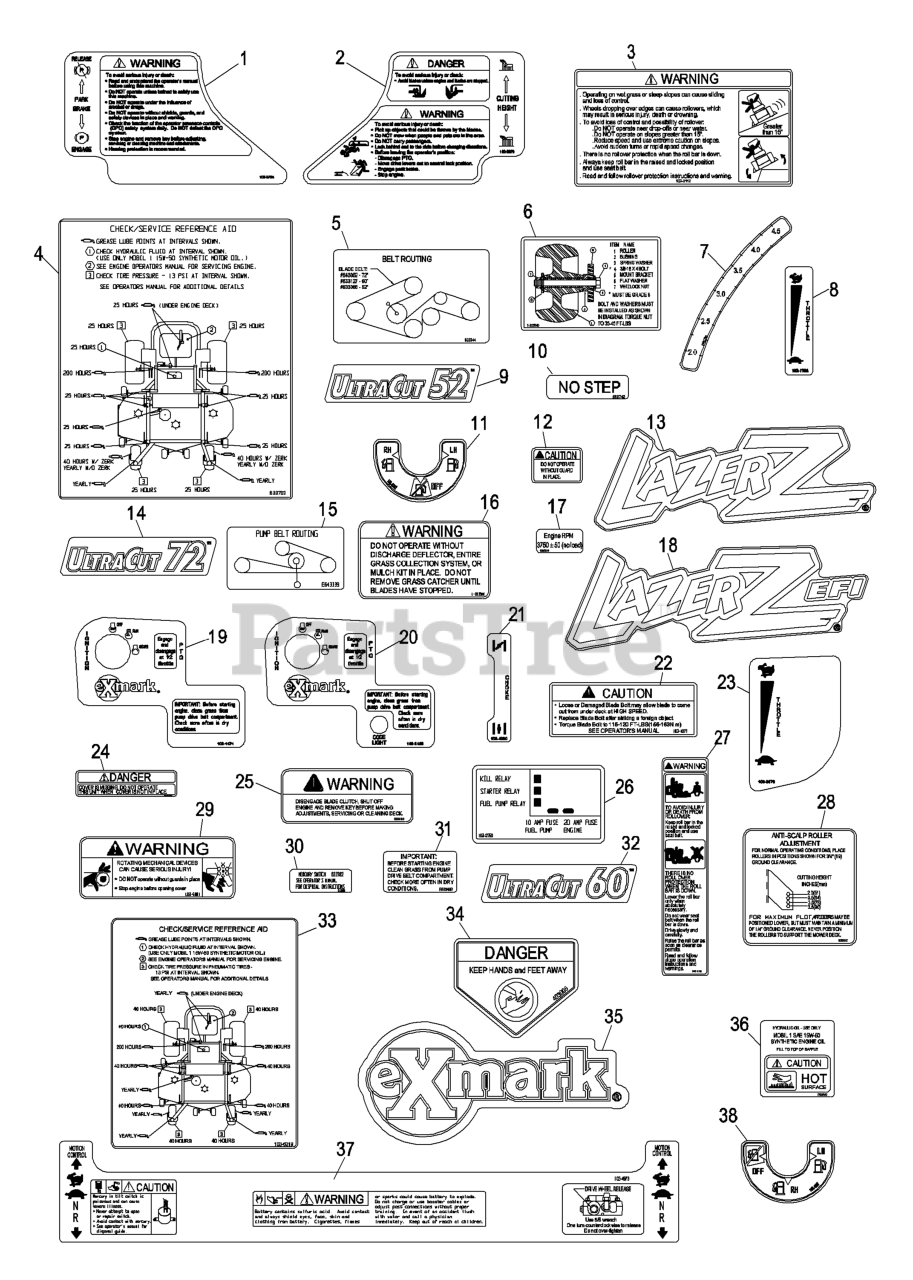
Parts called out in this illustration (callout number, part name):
1	DECAL,PARK BRAKE
2	DECAL,CUTTING HEIGHT
3	DECAL-WARNING
4	DECAL,CHECK/SERVICE
5	DECAL,BELT ROUTING
6	DECAL,ROLLER MOUNTING
7	DECAL-HEIGHT, DECK
8	DECAL,THROTTLE ONLY
9	DECAL,ULTRACUT 52
10	DECAL,NO STEP
11	DECAL-VALVE, FUEL
12	DECAL-GUARD
13	DECAL,LAZER MODEL
14	DECAL,ULTRACUT 72
15	DECAL-ROUTING, BELT
16	DECAL-WARNING, DISCHARGE
18	DECAL,EFI
19	DECAL,IGNITION/PTO
20	DECAL,IGNITION/PTO EFI
21	DECAL,CHOKE
22	DECAL,BOLT TORQUE
24	DECAL-COVER, MISSING
25	DECAL,WARNING
27	DECAL-WARNING, FOLDING RO
28	DECAL,ANTISCALP
29	DECAL-DEVICES, ROTATING
30	DECAL-SWITCH, MERCURY
31	DECAL-IMPORTANT
32	DECAL,ULTRACUT 60
33	DECAL,CHECK SERVICE LZ
34	DECAL-DANGER
35	DECAL,EXMARK LOGO
38	DECAL-VALVE, FUEL
